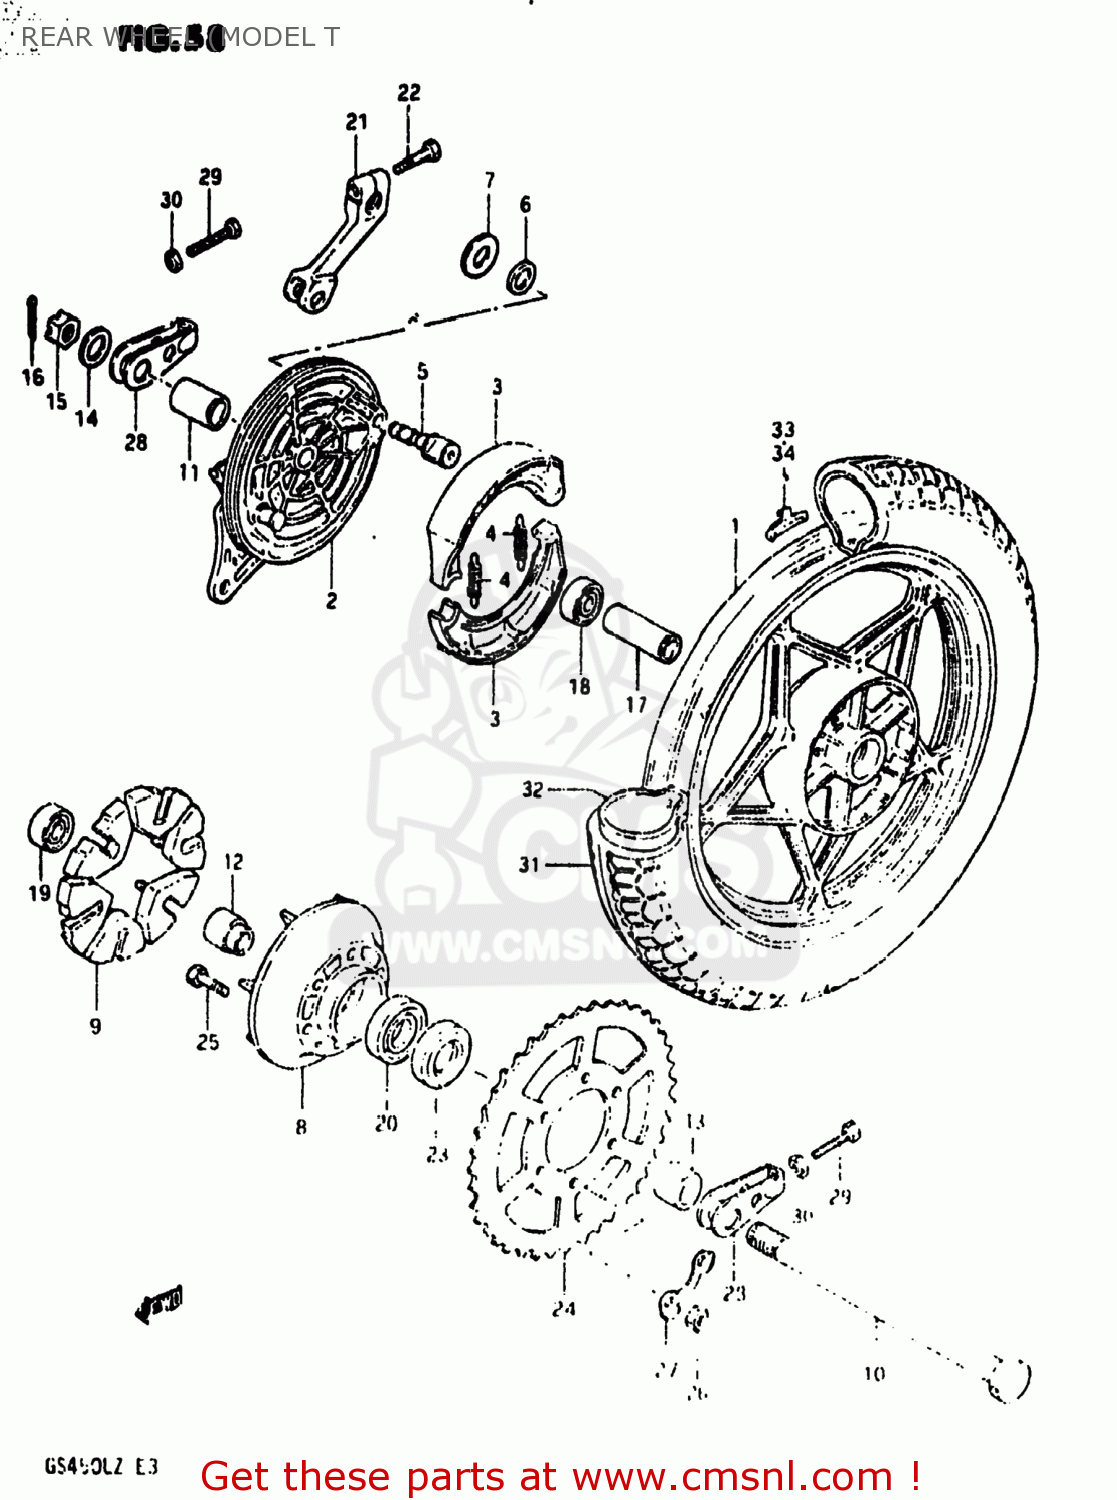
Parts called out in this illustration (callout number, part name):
1	WHEEL,REAR
2	PANEL,REAR HUB
3	SHOE,BRAKE
4	SPRING,BRAKE SHOE
5	CAM,FRONT BRAKE
6	O-RING,BOSS
7	WASHER (15X24X1.6)
8	DRUM,REAR SPROCKET MOUNT
9	ABSORBER,RR HUB SHOCK
10	AXLE,REAR
11	SPACER(17.5X28X44.8)
12	SPACER,REAR HUB BEARING
13	SPACER(17X30.5X22.3)
14	WASHER (17X30X3.2)
15	NUT
16	PIN,COTTER
17	SPACER (17.6X24X57)
18	BEARING
19	BEARING
20	BEARING
21	LEVER,RR BRAKE CAM
22	BOLT
23	SEAL,OIL(30.5X52X8)
24	SPROCKET,REAR (NT:41)
25	BOLT
26	NUT
27	WASHER
28	ADJUSTER,CHAIN
29	BOLT 8X50
30	NUT
31	TIRE
32	TUBE ASSY,WHEEL,INNER 4.60-16
33	BALANCER,WHEEL
34	BALANCER,WHEEL
